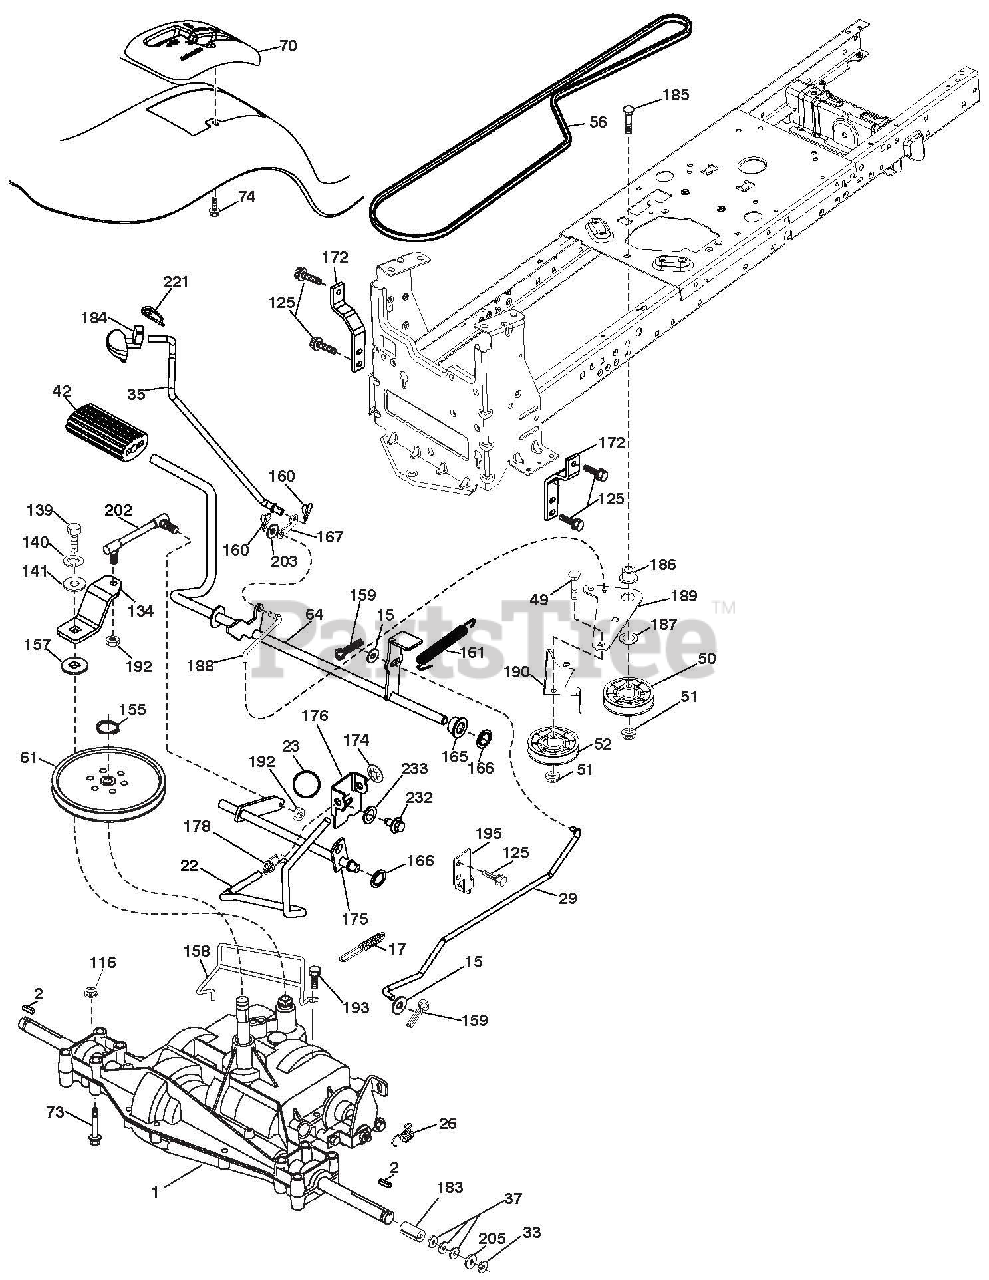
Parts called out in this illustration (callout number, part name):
2	KEY.SQUARE.2.0 X .1845/.1865
15	WASHER.13/32 X 13/16 X 16 GA.
17	SPRING.BRAKE.PEERLESS/D6800.TX
22	ROD.SHIFT.FENDER.TLT.2006
26	SPRING.BRAKE.RTN.GR DR.TEX.006
29	ROD.BRAKE.PEERLESS/D6800
33	E-RING.#5133-75
35	ROD.BRAKE.PARKING.LT.TEX
37	WASHER.25/32 X 1 1/4 X 16 GA.
42	COVER PEDAL BLK ROUND
49	BOLT.RDHD.3/8-16UNCX1-3/4.GR5
50	IDLER.FLAT.910"OFFSET
51	Nut, Hex, Flangelock 3/8-16
52	IDLER.V-GROOVE.910"OFFSET
56	V-BELT.DRV.97.40"PMST/DANA
61	PULLEY.TRANSAXLE.18/20"TIRES
64	SHAFT ASM.PEDAL.BRAKE CONTROL
70	CONSOLE SHIFT
73	BOLT 5/16-18 X 2 1/2 G.5
74	SCREW.HEX.WSH.HI-LO.1/4X1/2UNC
116	Nut, Lock Hex Flange 5/16-18 u
125	SCREW.5/16-18X3/4.SMGML.TAP/BL
134	ASM SHIFT
139	BOLT.1/4-28 UNF.GR8.W/PATCH
140	Washer, Lock 1/4
141	WASHER.9/32 X 3/4 X 10 GA.
155	Ring, Retainer
157	WASHER.PLATE.SHF..388 SQ.HOLE
158	KEEPER.T/A.PMS/D4360/D680.1820
159	PIN.COTTER.1/8 X 3/4.CAD.
160	RETAINER.CLIP(M).DIA.290
161	SPRING.RETURN.CLUTCH.6.75
165	BUSHING.SHAFT.BRAKE.HAND CONTR
166	NUT PUSH .625
167	LATCH.BRAKE.PARKING
172	STRAP.TRQ.LH.GEAR DRIVE.LT.TEX
174	NUT.PUSH..500
175	SHAFT ASM. SHIFT GEAR DRIVE
176	ARM.CLEVIS.ROD.SHIFT
178	SPRING.SHIFT.GT.2006
183	SPACER.AXLE.HYDRO/PEERLES
184	HANDLE.PARKING
185	BOLT.RDHD.3/8-16UNC X2-3/4 GR5
186	SPACER.RETAINER
187	WASHER.13/32 X 2 X 10 GA.
188	LINK.CLUTCH.GROUND DRIVE
189	BELLCRANK.GROUNDRIVE.NSTG/NSTL
190	KEEPER.BELLCRANK.DRIVE.GROUND
192	NUT.LOCK.CENTER.1/4-28 FNTHD.
193	SCREW.5/16-18X3/4.SMGML.TAP/R
195	BRACKET.ROD.BRK.PEERLESS/D6800
203	Washer 11/32 x 11/16 x 16 Ga.
205	WASHER.25/32 X 1-5/8 X 16GA.
221	RETAINER.SPRING.CLIP.HANDLE
232	BOLT.FIN HEX.7/16-14X1 GR5
233	WASHER.SERRATED
